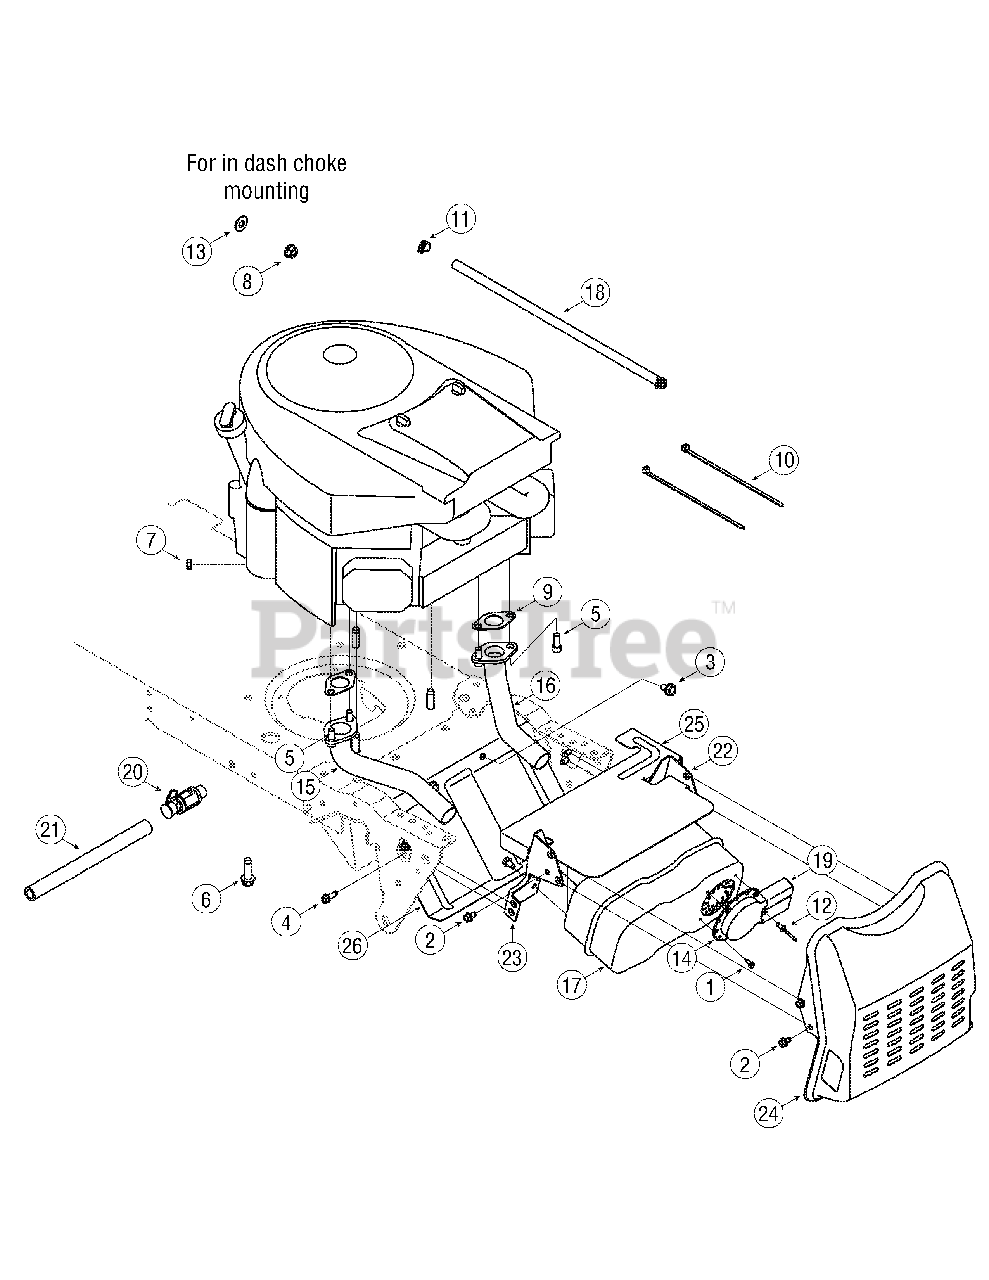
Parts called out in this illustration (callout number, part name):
1	AB Screw #8-18 x 0.5
2	TT Screw 1/4-20 x 0.5
3	TT Screw 5/16-18 x 0.625
4	TT Screw 1/4-20 x 0.625
5	Screw, 5/16-18 x .750
6	TT Screw 3/8-16 x 1.25
7	Sems Nut, 1/4-20
8	Flange Lock Nut, 3/8-16
9	Exhaust Gasket
10	Cable Tie
11	Hose Clamp
13	Flat Washer, .406 x .875 x .059
14	Muffler Deflector
15	RH Exhaust Pipe
16	LH Exhaust Pipe
17	Dual Inlet Muffler
18	Fuel Line Hose
19	Muffler Deflector, Long
20	Oil Drain Valve
21	OIl Drain Extension Hose
25	Heat Shield, Twin
26	Muffler Heat Shield
